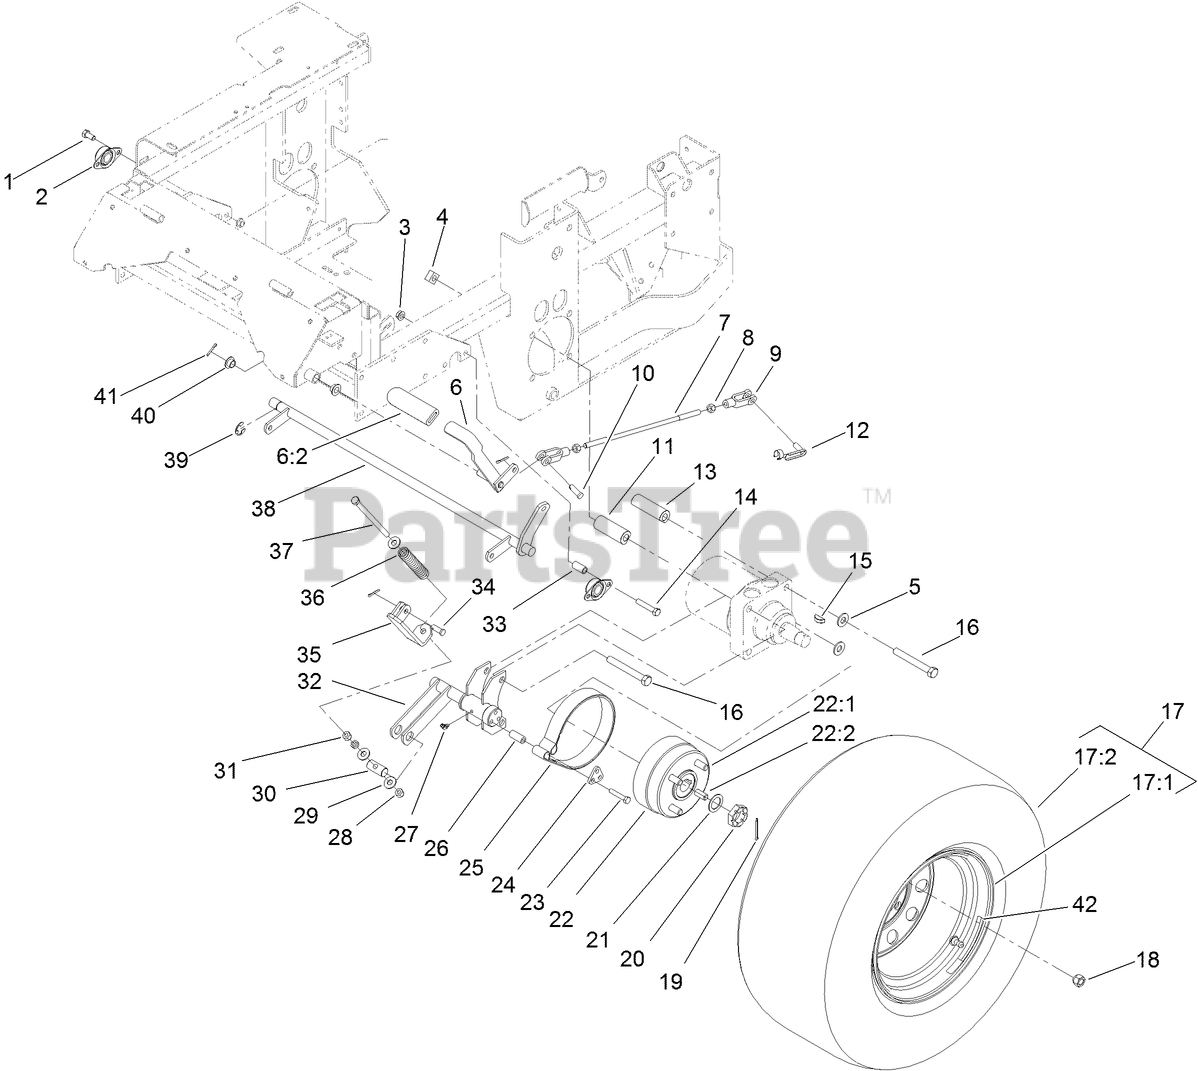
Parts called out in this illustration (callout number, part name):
1	SCREW-HH
2	BEARING-FLANGE, SIDE
3	NUT-HHF, WHIZ
4	NUT-SQUARE, SPECIAL
5	WASHER-THRUST
6	BRAKE LEVER AND GRIP ASM
6:2	GRIP-LEVER
7	ROD-BRAKE
8	NUT-HEX
9	YOKE-LINKAGE, BRAKE
10	PIN-CLEVIS
11	SPACER-WHEEL, SHORT
12	Pin-Spring, Clevis
13	SPACER-WHEEL, LONG
14	SCREW-HH
15	KEY-WOODRUFF
16	SCREW-HH
17	WHEEL AND TIRE ASM
18	NUT-LUG
19	PIN-COTTER
20	NUT-HH
21	WASHER-SPACER
22	WHEEL HUB ASM
22:1	HUB-WHEEL
22:2	STUD-WHEEL
23	SCREW-HH
24	RETAINER-BAND, BRAKE
25	BAND-BRAKE
26	SPACER
27	FITTING-GREASE
28	NUT-LOCK, NI
29	WASHER-FLAT
30	PIN-TRUNION
31	NUT-JAM
32	BRAKE-NARROW
33	SPACER-RETAINER, BRAKE
34	PIN-CLEVIS
35	LINKAGE-BRAKE, LOWER
36	SPRING-BRAKE
37	BOLT-TAP, HH
38	SHAFT-BRAKE
39	E-RING
40	BEARING-CONTROL
41	PIN-COTTER
42	DECAL
